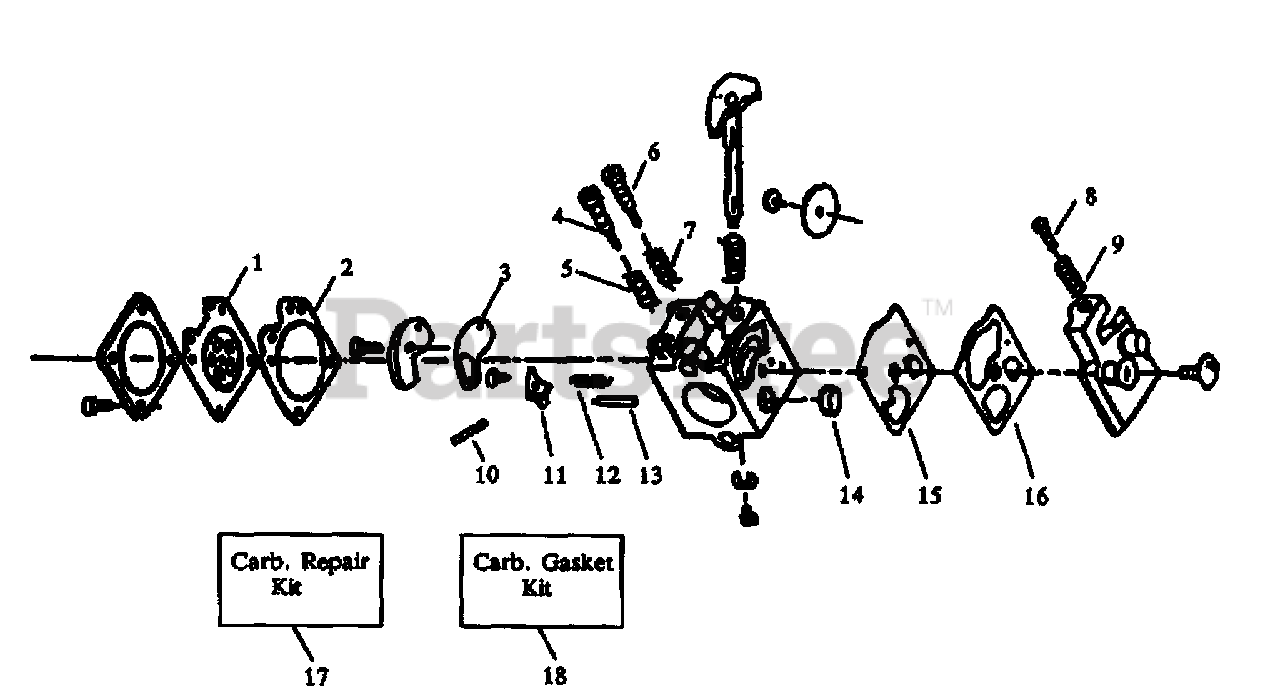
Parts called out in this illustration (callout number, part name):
1	Metering Diaphragm
2	Metering Diaphragm Gasket
3	Circuit Plate Gasket
4	Hi Speed Needle
5	Hi Speed Needle Spring
6	Idle Needle
7	Idle Needle Spring
8	Idle Speed Screw
9	Idle Speed Spring
10	Metering Pin
11	Metering Lever
12	Metering Lever Spring
13	Inlet Needle Valve
14	Inlet Screen
15	Pump Diaphram
16	Pump Gasket
17	Carb Kwik Repair Kit
18	Carb. Gasket/Diaphragm Kit
